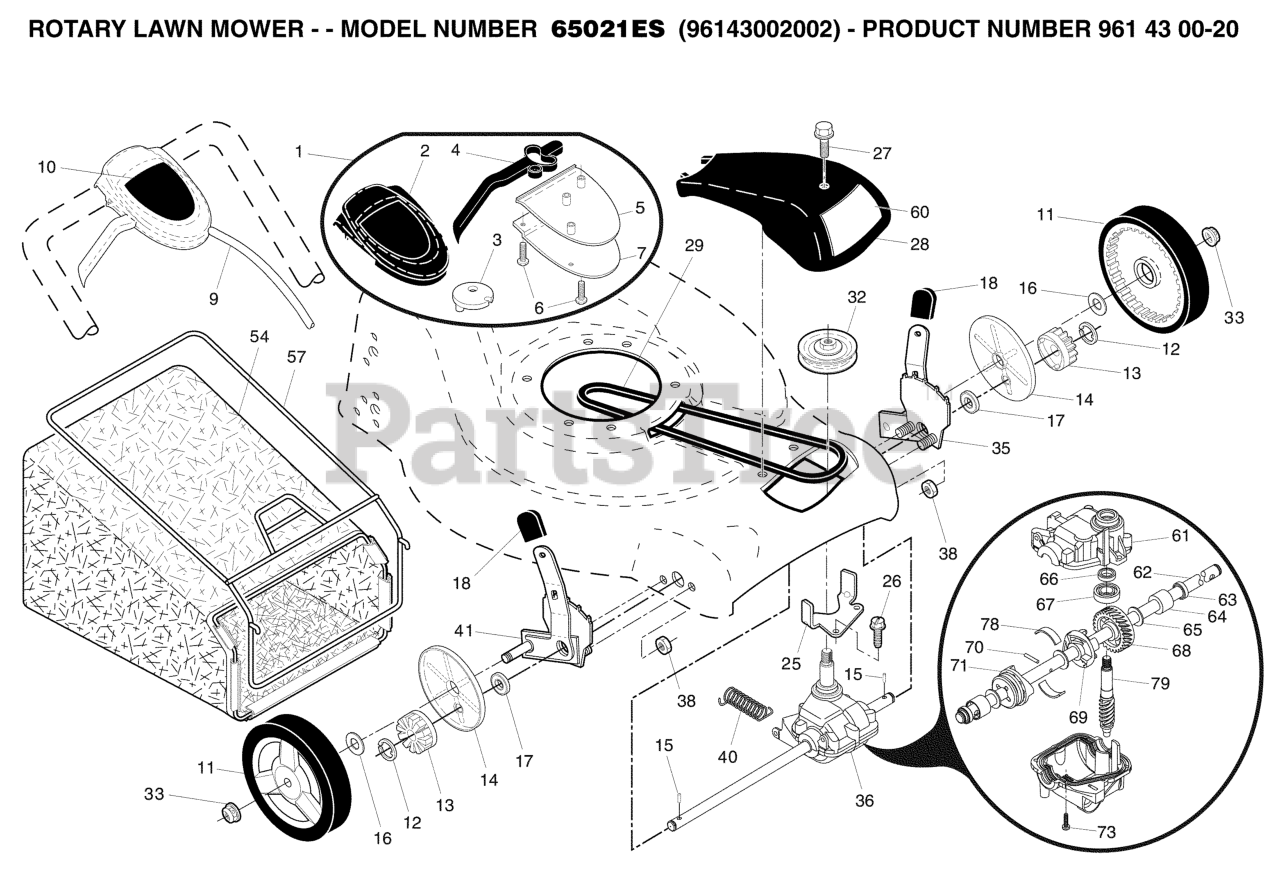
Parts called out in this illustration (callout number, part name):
1	DRIVE CONTROL ASSEMBLY (INCLUD
2	COVER.TOP.DRIVE.CONTROL.BLACK
3	PULLEY
4	Lever, Drive Control
5	COVER.BOTTOM.DRIVE.CNTRL.BLACK
6	SCREW, PHILLIPS HEAD 10 X 5/8
7	BRACKET.DRIVE.CONTROL.MOUNT.BL
9	CABLE ASSEMBLY, DRIVE
10	DECAL, DRIVE
11	WHEEL.8X1.75.H3SPK.RAD3.GY.BU3
12	E-RING 7/16 RE
13	PINION.14.TEETH.FGD
14	COVER.DUST.WHEEL
15	PAWL, DRIVE
16	WASHER FLUT
17	BEARING
18	KNOB.DELUXE.GRAY
25	BELT KEEPER
27	SCREW, HEX HD TAPPING #10-24 1
28	COVER.DR.21.FWGD/B&S.GRAY
29	BELT.DRIVE.FG
32	RP PULLEY.DRIVE.EZ
33	HEX FLANGE LOCKNT
35	WHEEL ADJ KIT LH
36	TRANSMISSION.21.FGD.HT.VST
38	LOCKNUT.NYLOC.1/4-20
41	WHEEL ADJ KIT RH
54	GBAG.34710247.SILVER.H
57	FRAME, GRASSBAG
60	DECAL DRIVE COVER
61	CASE.UPPER.00254(SERVICE)
62	SHAFT OUTPUT (12289)
63	SEAL.OUTPUT.SHAFT
66	SEAL INPUT SHAFT
68	GEAR 28 TEETH 36208
69	FIXED DOG CLUTCH
70	PIN.3.50.33733
71	MOVEABLE DOG CLUTCH
74	CASE.BOTTOM.
78	SPRING LEAF
79	SHAFT WORM
